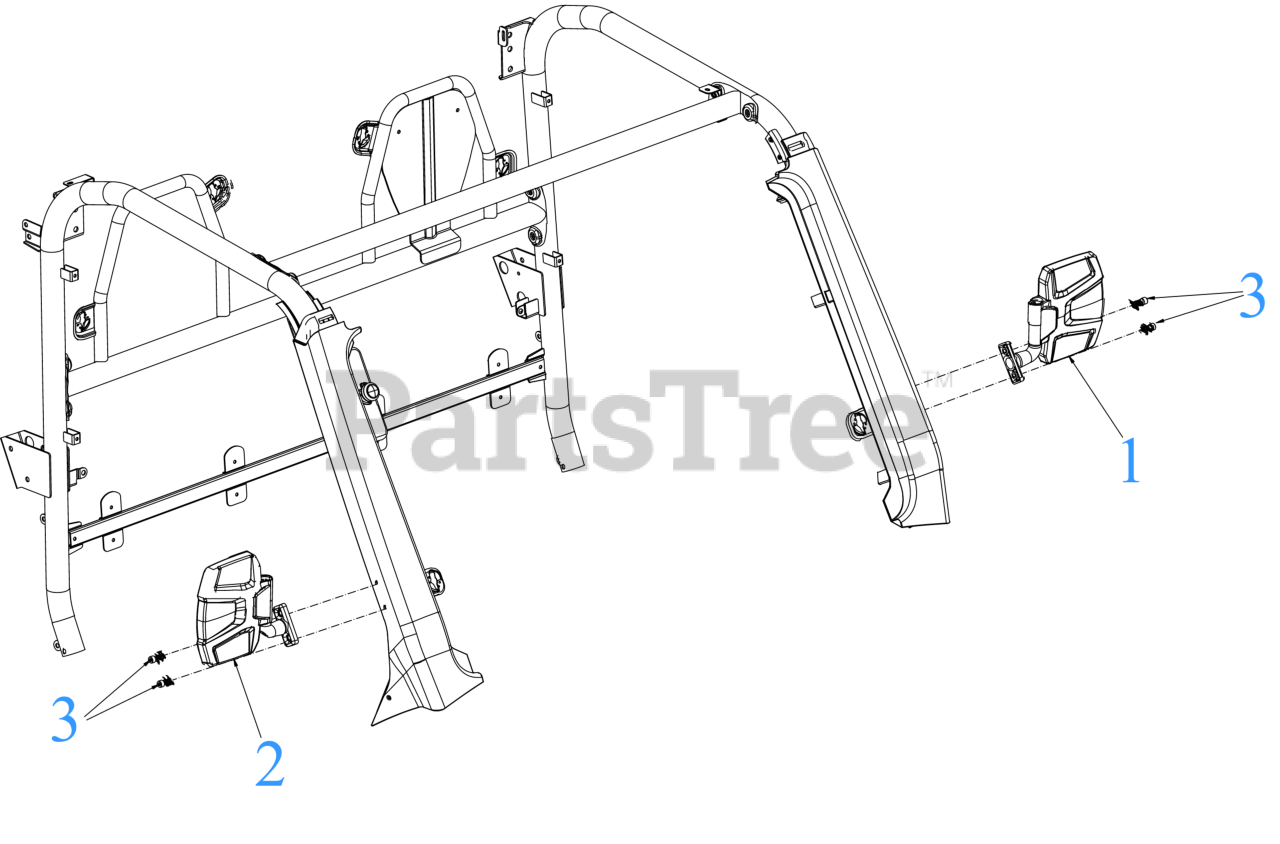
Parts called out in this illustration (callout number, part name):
1	REARVIEW MIRROR KIT - LEFT
2	REARVIEW MIRROR KIT - RIGHT
3	HEX HEAD CAP SCREW M8X25
